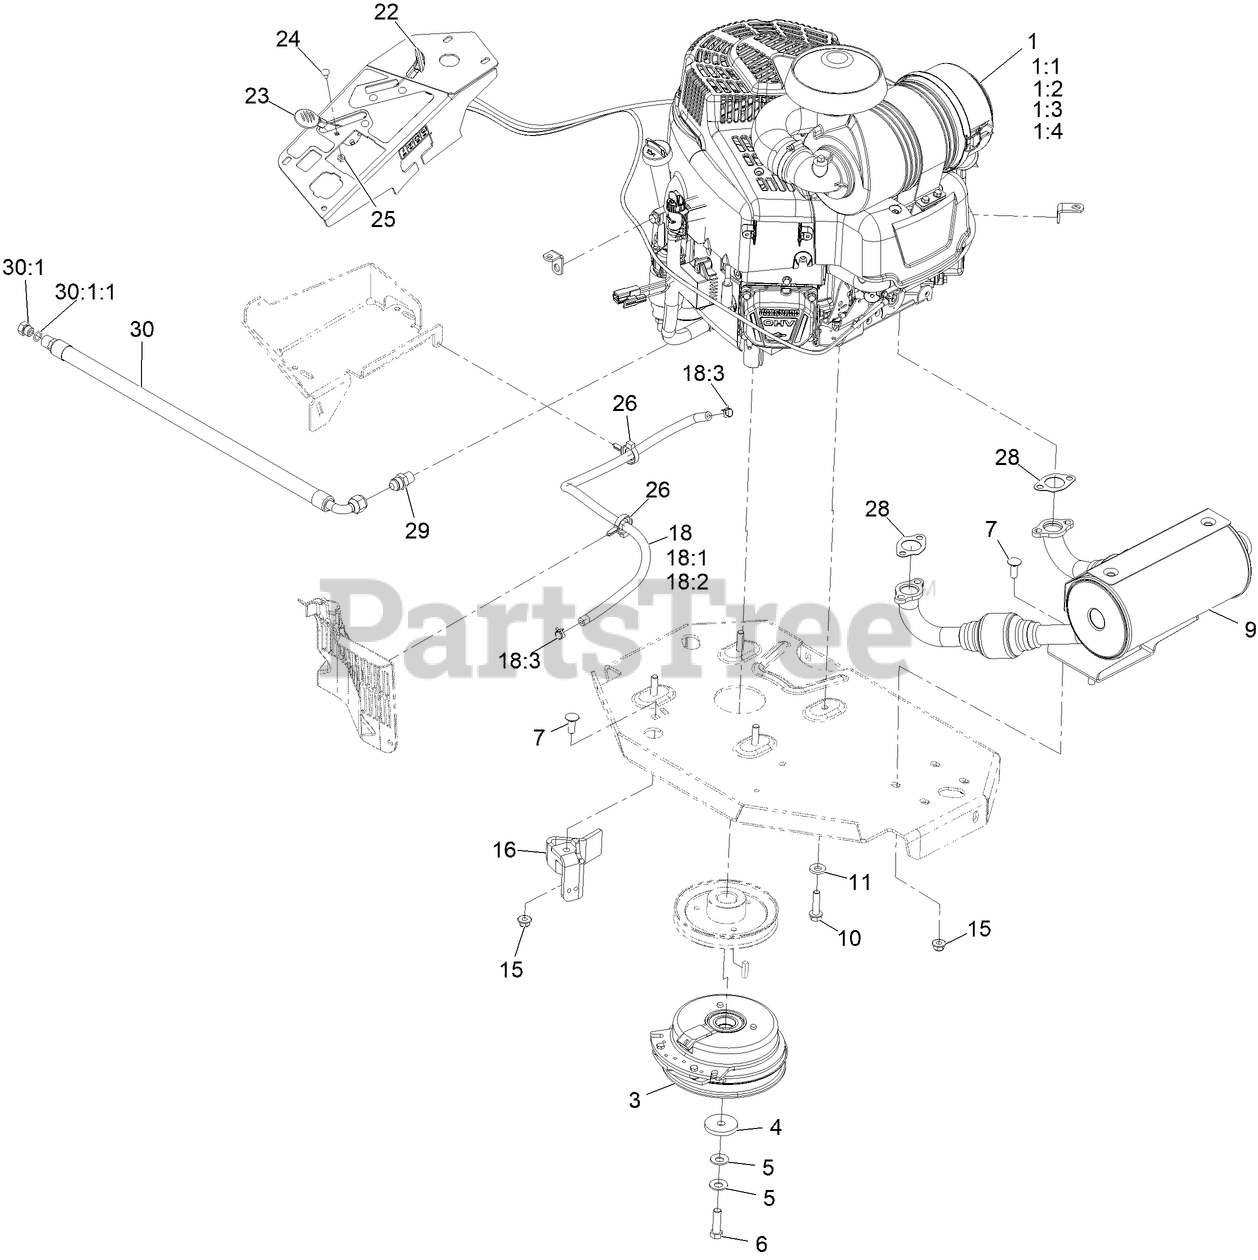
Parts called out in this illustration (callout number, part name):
1	Engine, 810 Vanguard Carb
1:4	Filter-Fuel
3	CLUTCH KIT
4	WASHER-CLUTCH
5	WASHER-SPRING
6	SCREW-HH 7/16-20 X 1 1/2 W/LOCTITE
7	SCREW-CARR
9	KIT, MUFFLER
10	SCREW-HWH
11	WASHER-BELLEVILLE
15	NUT-HF, NI
16	CLUTCH-ANCHOR
18	FUEL LINE ASM
18:1	HOSE-FUEL
18:2	SLEEVE-THERMAL
18:3	CLAMP-HOSE
22	CABLE-CONTROL, CHOKE
23	ASM,THROTTLE CABLE
24	BOLT-CARR
25	NUT-LOCK, NI
26	CLAMP-HOSE
28	Gasket, Exhaust
29	FITTING-STRAIGHT
30	ASM, Oil Drain Hose W/Plug
30:1	PLUG-HH
30:1:1	O-RING
